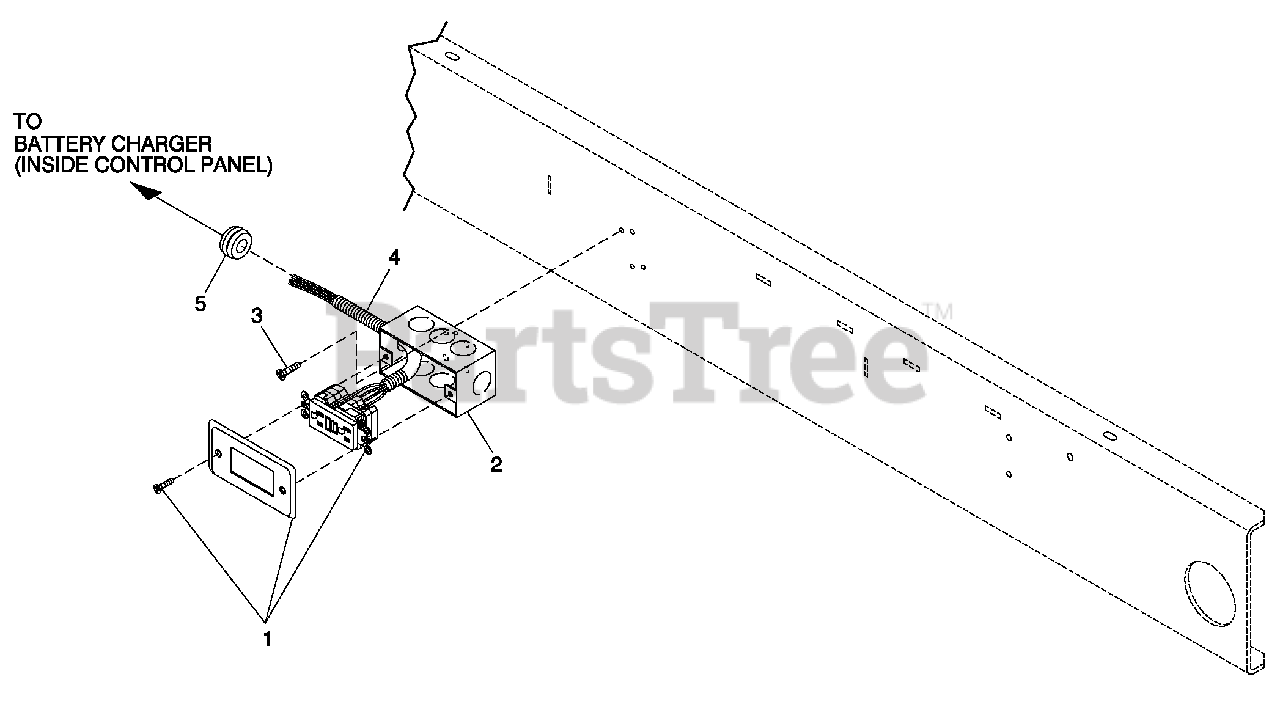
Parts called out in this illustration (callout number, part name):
1	OUTLET 20A GFCI
2	BOX HANDY 2-1/8 X 4
3	SCREW HHTT #10-24 X 3/8 CZ
4	HARN ALT CON BOX 1PH QT
5	GROMMET .87 X .25 X .62
